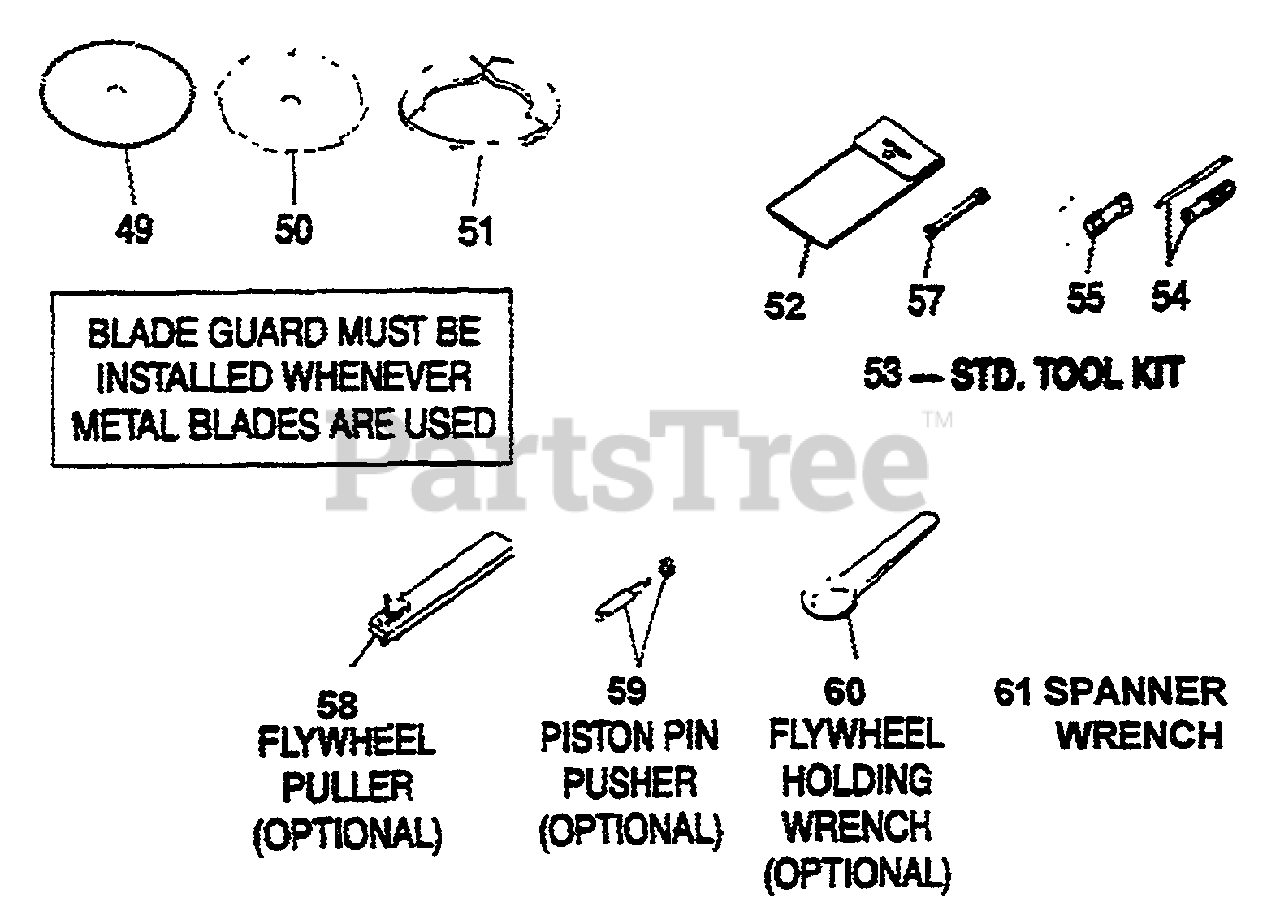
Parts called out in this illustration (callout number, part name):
49	SAW BLADE
50	BRUSH BLADE
51	BLADE COVER
53	TOOL KIT
54	SCREW DRIVER
58	FLYWHEEL PULLER
59	PISTON PIN PUSHER
60	SPANNER, FLYWHEEL
